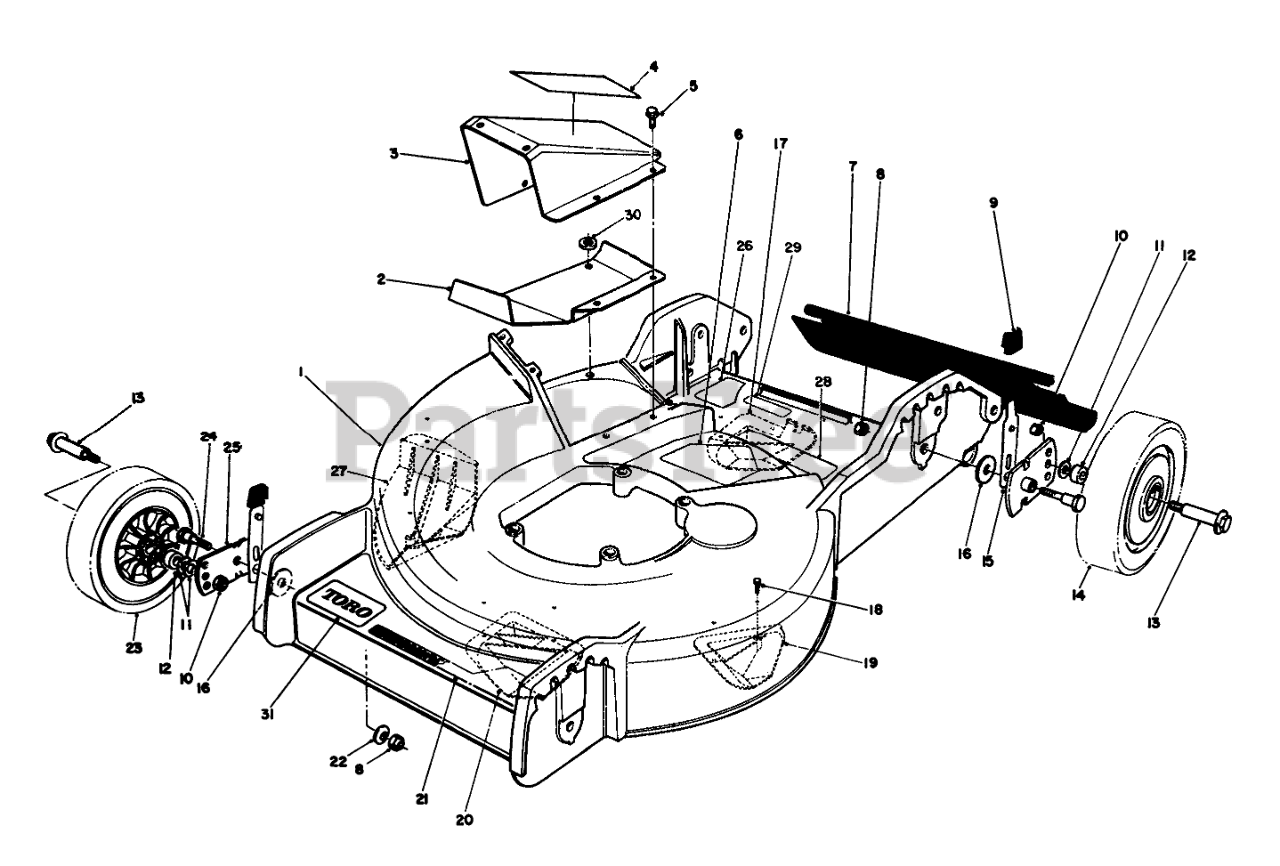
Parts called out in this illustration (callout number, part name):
1	Housing-18-(Incl. Ref. #6, 17-20, & 26-29)
2	DISCHARGE KICKER
3	Cover-Discharge (Incl. Ref. #4)
4	DECAL - COVER
5	SCREW
6	DECAL-DANGER
7	SHIELD - TRAILING
8	NUT-LOCK, NI
9	KNOB-ARM
10	NUT-HEX
11	WASHER
12	WHEEL SPACER
13	BOLT-WHEEL
14	8" WHL & TIRE ASM
15	SPRING ARM ASM
16	PIVOT WASHER
17	KICKER
18	SCREW-PPH
19	KICKER
20	KICKER
21	DECAL - DECK
22	WASHER-BELLEVILLE
23	7" WHL & TIRE ASM
24	5/16-18 PIVOT SCREW
25	PIVOT ARM ASSY
26	DECAL - DANGER
27	KICKER
28	DECAL - DANGER
29	DECAL-WARNING
30	WASHER-FLAT
31	DECAL
